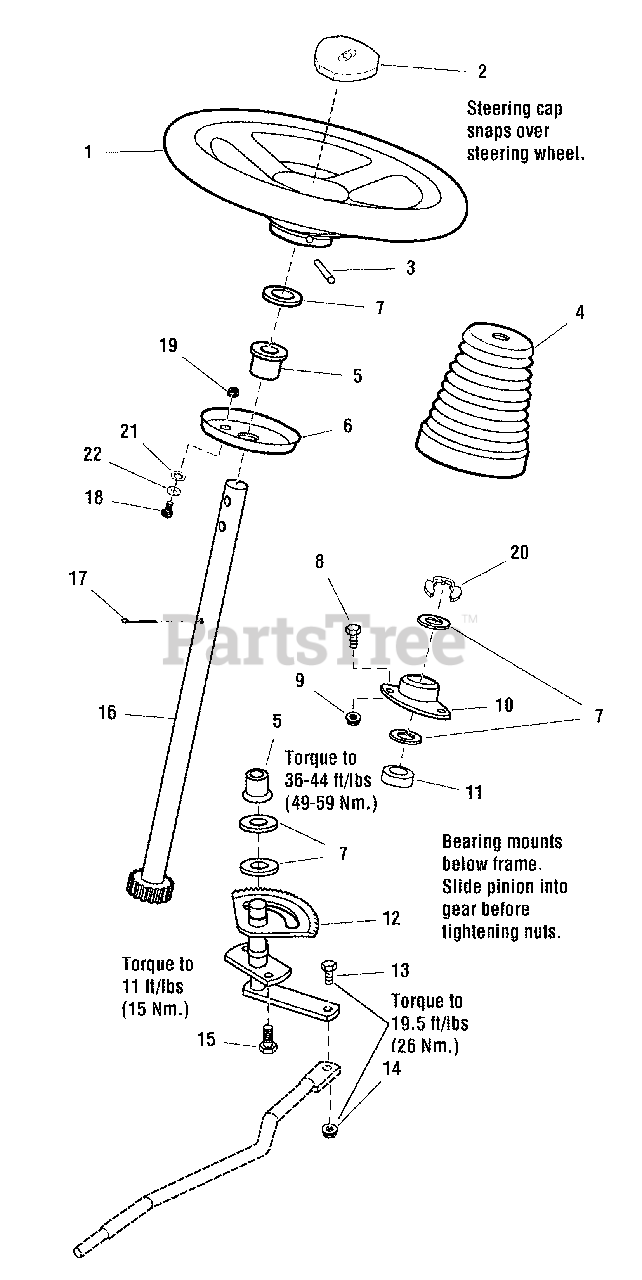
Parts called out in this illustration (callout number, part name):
1	STEERING WHEEL, Straight Shaft
2	CAP, Steering Wheel, Simplicity
2	CAP, Steering Wheel, Plain
3	PIN, Spring
4	COVER, Black Rubber
6	PLATE, Mounting Steering
7	WASHER
8	CAPSCREW, Hex Head Flange Lock, 3/8-16 x 3/4
9	NUT, Hex Whiz Lock, 3/8-16
10	BEARING, Flange
12	GEAR & SHAFT ASSEMBLY
13	CAPSCREW, Hex Head, 3/8-16 x 1-1/4
14	NUT, Hex Flange Lock, 3/8-16
15	CAPSCREW, Hex Head Taptite, 5/16-18 x 3/4
16	SHAFT ASSEMBLY
17	PIN, Cotter
18	CARRIAGE BOLT, 1/4-20 x 3/4
19	NUT, Hex,1/4-20
20	RING, Clipring Extension
21	WASHER
22	NUT, Push, 5/16
